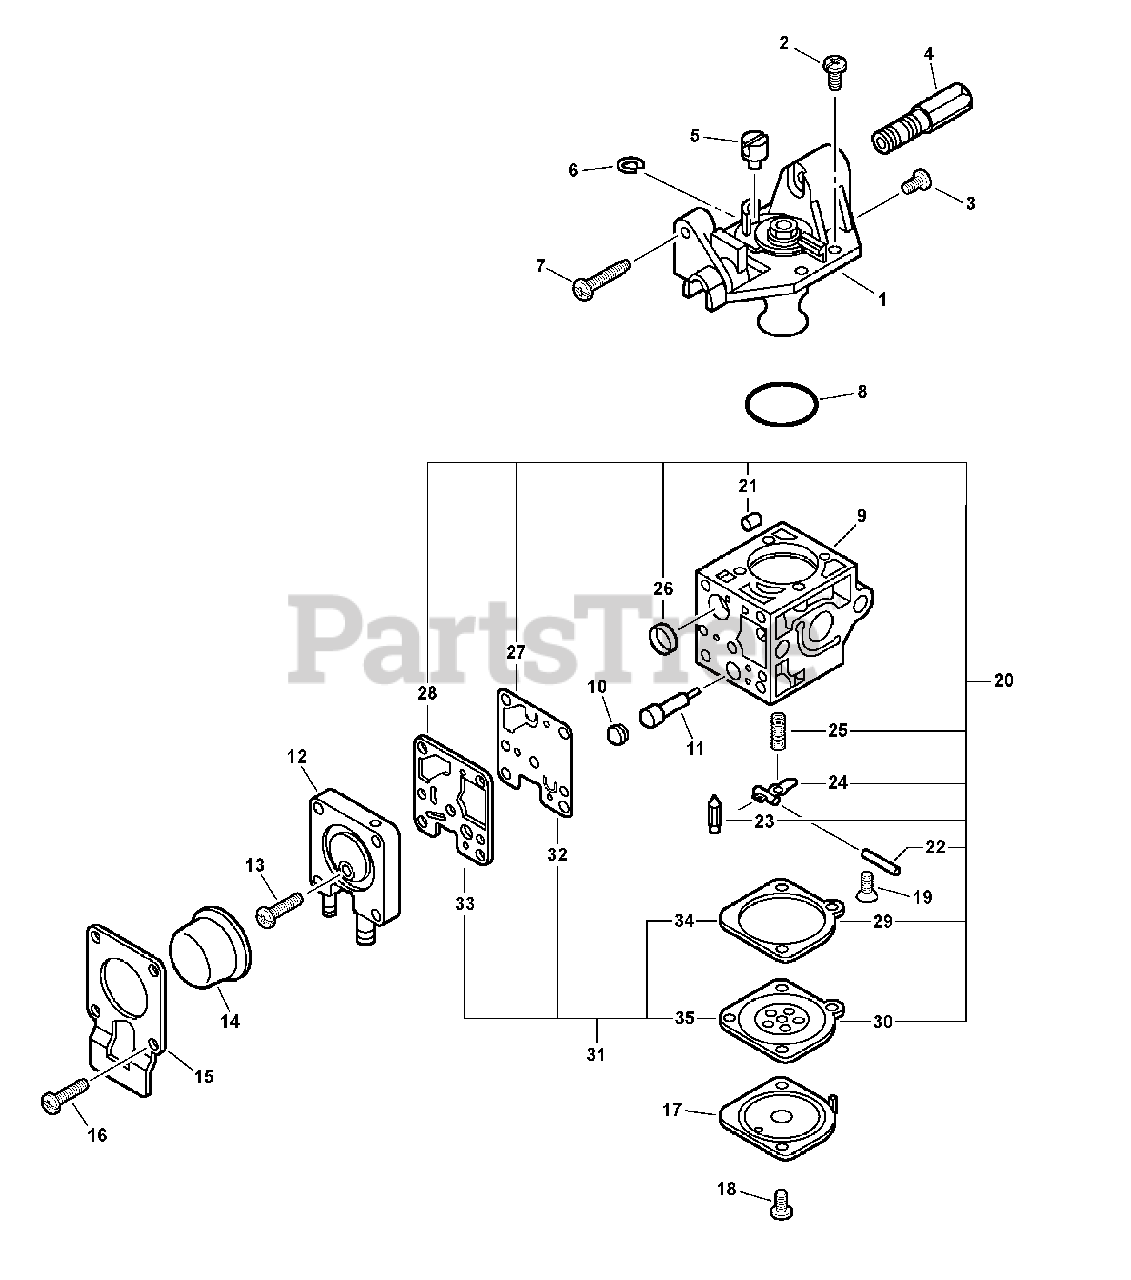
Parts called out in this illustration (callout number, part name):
1	COVER ASSY, ROTOR
4	ADJUSTER, THROTTLE CABLE
5	SWIVEL
7	SCREW, IDLE ADJUST
9	BODY, CARBURETOR
11	NEEDLE, HIGH SPEED
12	BODY ASSY, PURGE
14	BULB, PURGE
15	RETAINER, PURGE BULB
16	SCREW
17	COVER, METERING DIAPHRAGM
20	REBUILD KIT
21	GUIDE, ROLLER
22	PIN, METERING LEVER
23	VALVE, INLET NEEDLE
24	LEVER, METERING
25	SPRING, METERING LEVER
26	STRAINER
27	DIAPHRAGM, PUMP
28	GASKET, PUMP
29	GASKET, METERING
30	DIAPHRAGM, METERING
31	GASKET / DIAPHRAGM KIT
32	DIAPHRAGM, PUMP
33	GASKET, PUMP
34	GASKET, METERING
35	DIAPHRAGM, METERING
